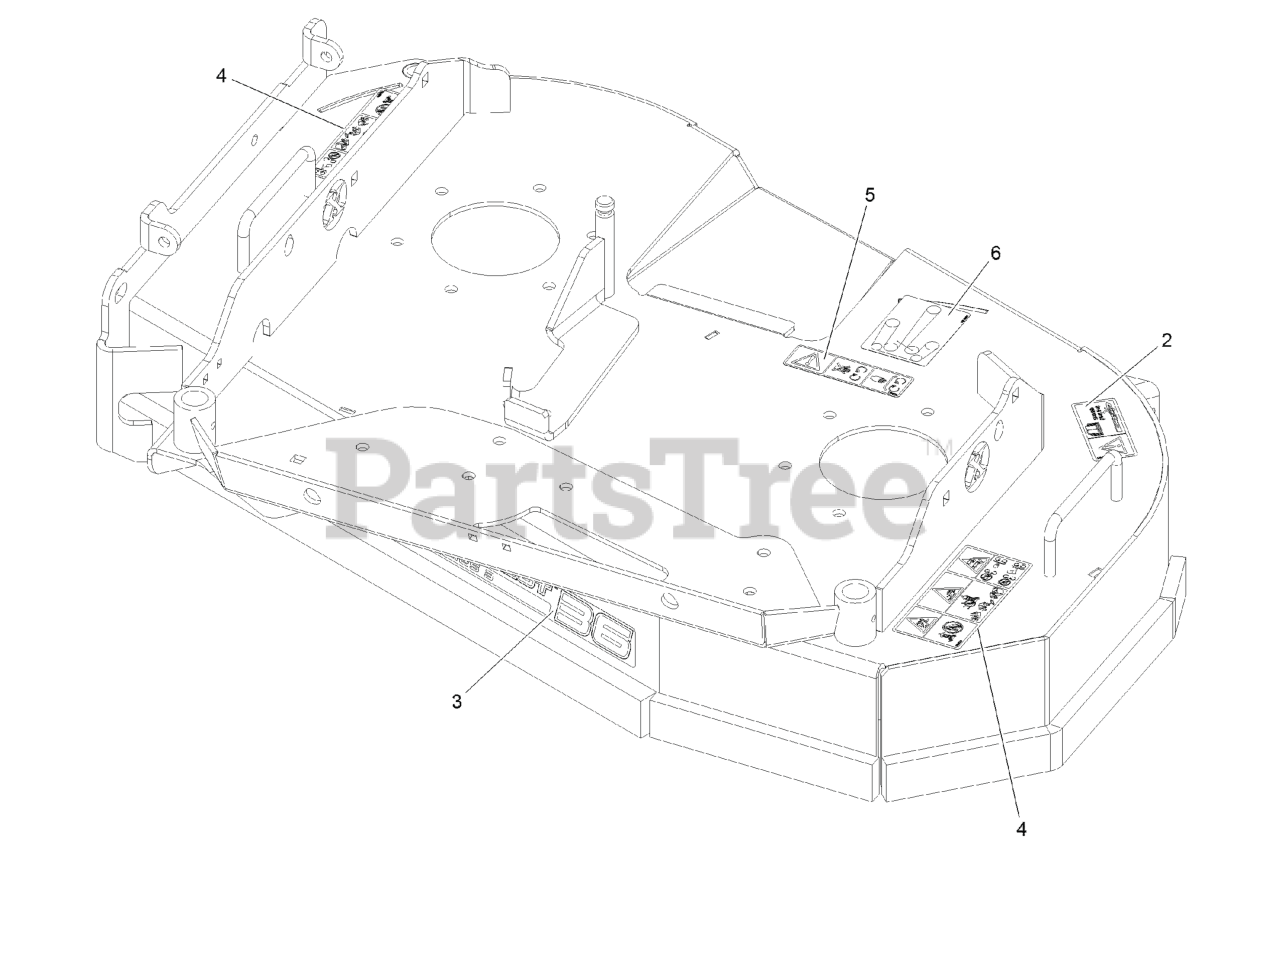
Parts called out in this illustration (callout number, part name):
2	DECAL-TORQUE, BOLT
3	DECAL-ULTRACUT 36 SERIES 3
4	DECAL-WARNING THROWN OBJ
5	DECAL-COVER, MISSING
6	DECAL-BELT ROUTING
